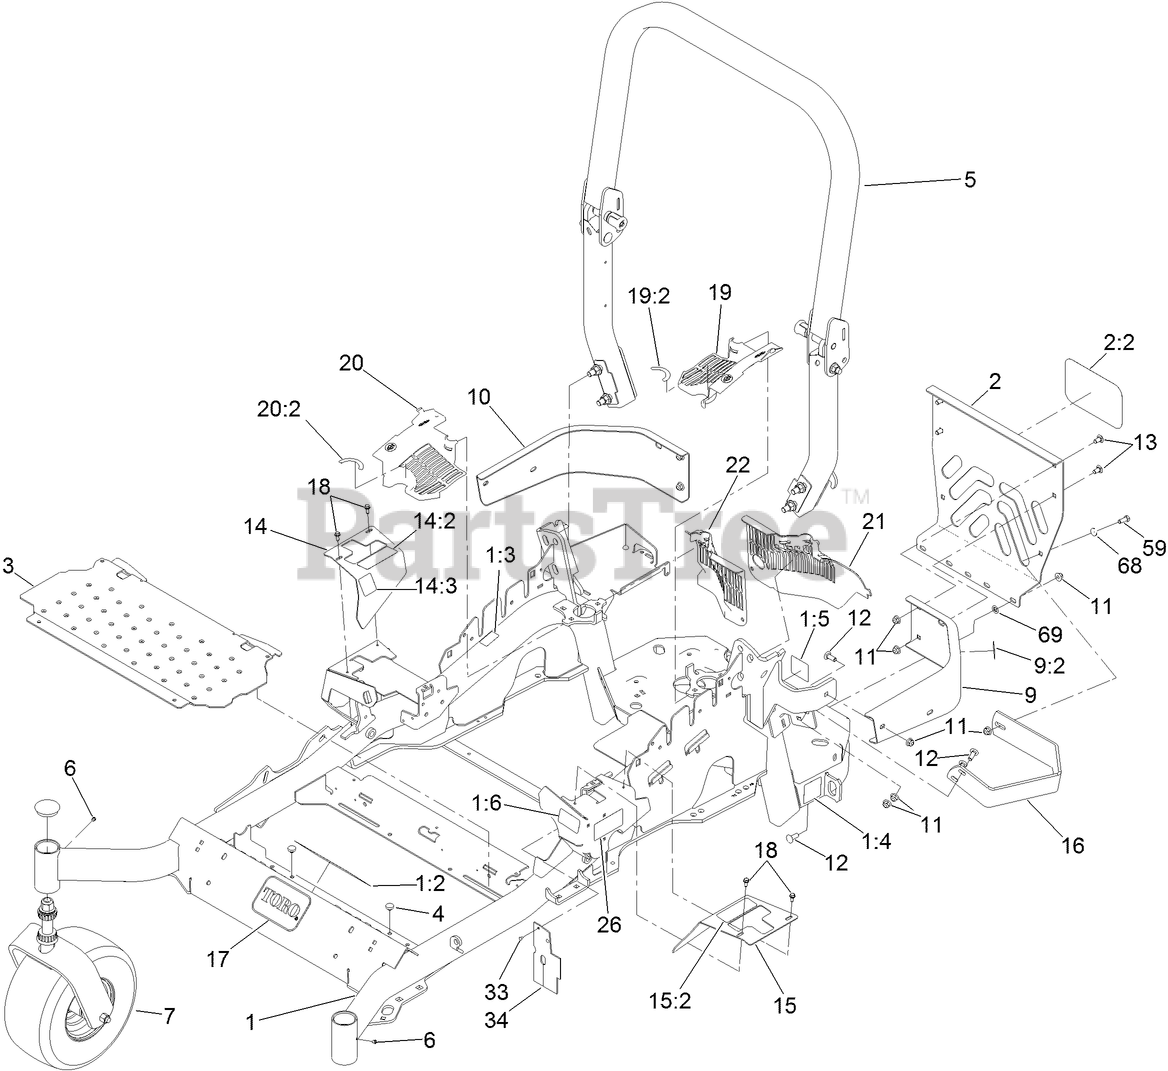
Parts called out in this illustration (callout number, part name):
1	MAINFRAME ASM
1:2	DECAL-CAUTION
1:3	DECAL-SLOPE
1:4	DECAL-BELT DRIVE
1:5	DECAL-SPARK ARRESTER
1:6	DECAL-FUEL FILL
2	REAR GUARD ASM
2:2	DECAL
3	FLOORPAN
4	BUMPER
5	ROPS ASM
7	Caster Wheel ASM
9	LH BUMPER ASM
9:2	DECAL-CAUTION
10	BUMPER-RH
11	NUT-HF, NI
12	SCREW-CARR
13	SCREW-CARR
14	RH MOTION CONTROL COVER ASM
14:2	DECAL-MOTION CONTROL
14:3	DECAL-PARK BRAKE
15	LH MOTION CONTROL COVER ASM
15:2	DECAL-MOTION CONTROL
16	GUARD-MUFFLER
17	DECAL
18	SCREW-HWH
19	LH HYDRO GUARD ASM
19:2	DECAL-HYDRO OIL
20	RH HYDRO GUARD ASM
20:2	DECAL-HYDRO OIL
21	GUARD-HYDRO REAR, LH TRIM
22	GUARD-HYDRO, REAR (RH)
33	RIVET-POP
34	DEFLECTOR-AIR FLOW
59	SCREW-HH
68	WASHER-FLAT
69	NUT-PUSH
